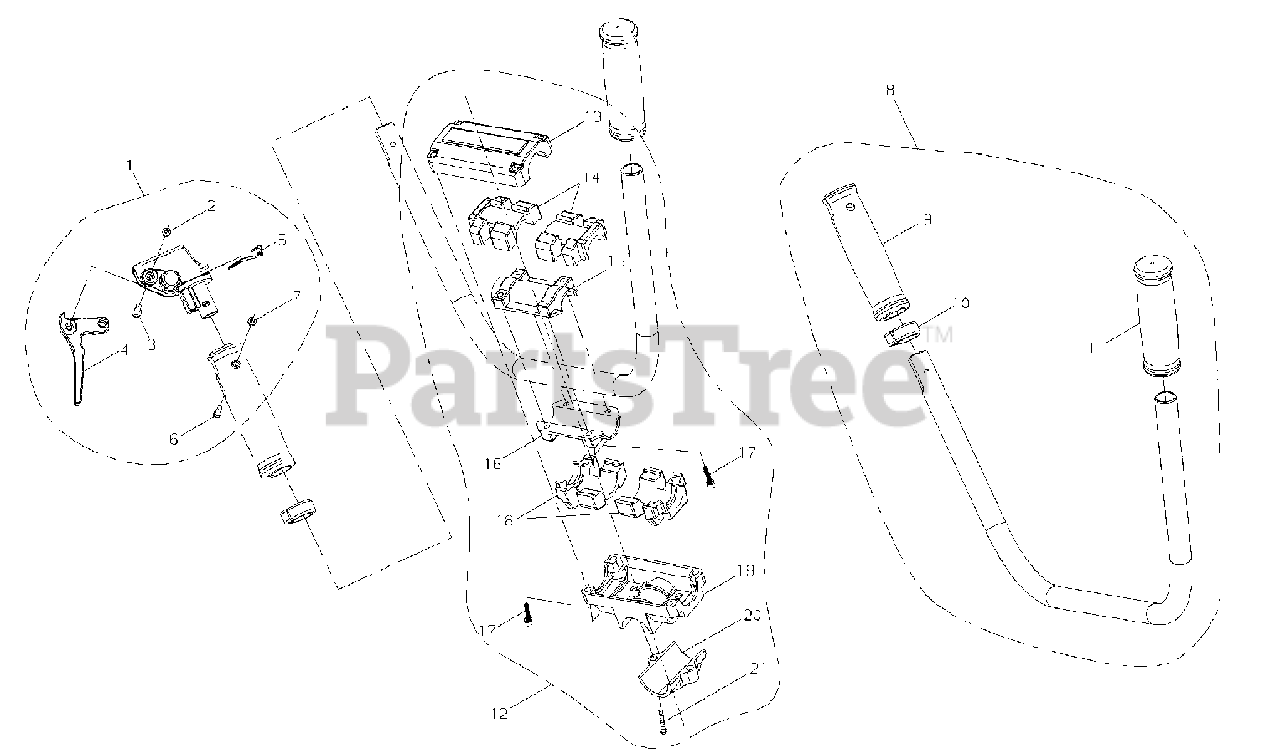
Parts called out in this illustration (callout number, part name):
1	THROTTLE CONTROL ASSY
2	LOCKNUT - 5
3	BOLT
4	TRIGGER, THROTTLE
5	THROTTLE LEVER STOPPER
6	SCREW - 4X24
7	NUT - 4 -- NYLON
8	HANDLE ASSY
9	GRIP - RIGHT
10	HOLDER, CABLE
11	GRIP - LEFT
12	HANDLE BRACKET KIT
13	BRACKET, HANDLE - UPPER
14	CUSHION - UPPER
15	CLAMP - UPPER
16	CLAMP - LOWER
17	SCREW - 5X25
18	CUSHION - LOWER
19	BRACKET, HANDLE - LOWER
20	BRACKET, HANDLE - UPPER
21	SCREW - 6X25
